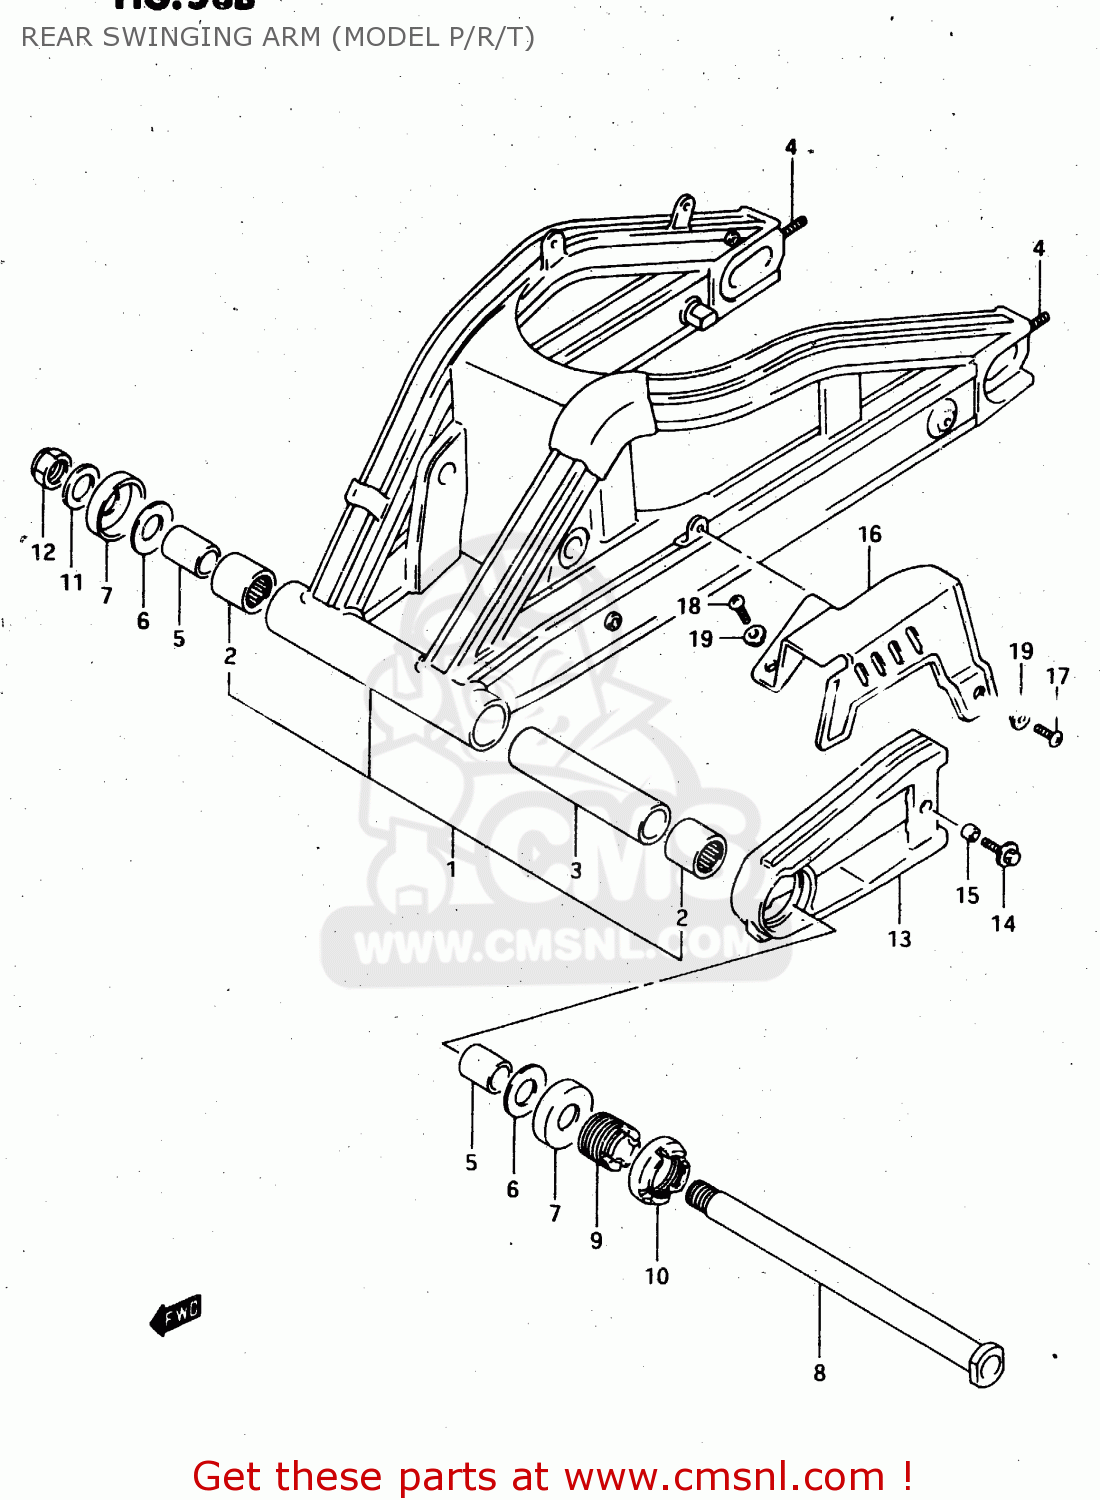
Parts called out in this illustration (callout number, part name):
1	SWINGINGARM ASSY,RR
2	BEARING(25X33X30)
3	SPACER,RR SWGARM PIVOT CTR
4	STUD,CHAIN ADJUSTER BOLT
5	SPACER,RR SWGARM PIVOT BERRING
6	WASHER
7	DUST SEAL,RR SWGARM PIVOT
8	SHAFT,RR SWINGINGARM PIVOT
9	BOLT,RR SWGARM PIVOT
10	NUT,REAR SWING ARM PIVOT
11	WASHER
12	NUT
13	BUFFER,CHAIN TOUCH DEFENSE
14	BOLT 6X20,WITH PLAIN WASHER
15	SPACER
16	CASE,CHAIN
17	SCREW
18	SCREW
19	WASHER
